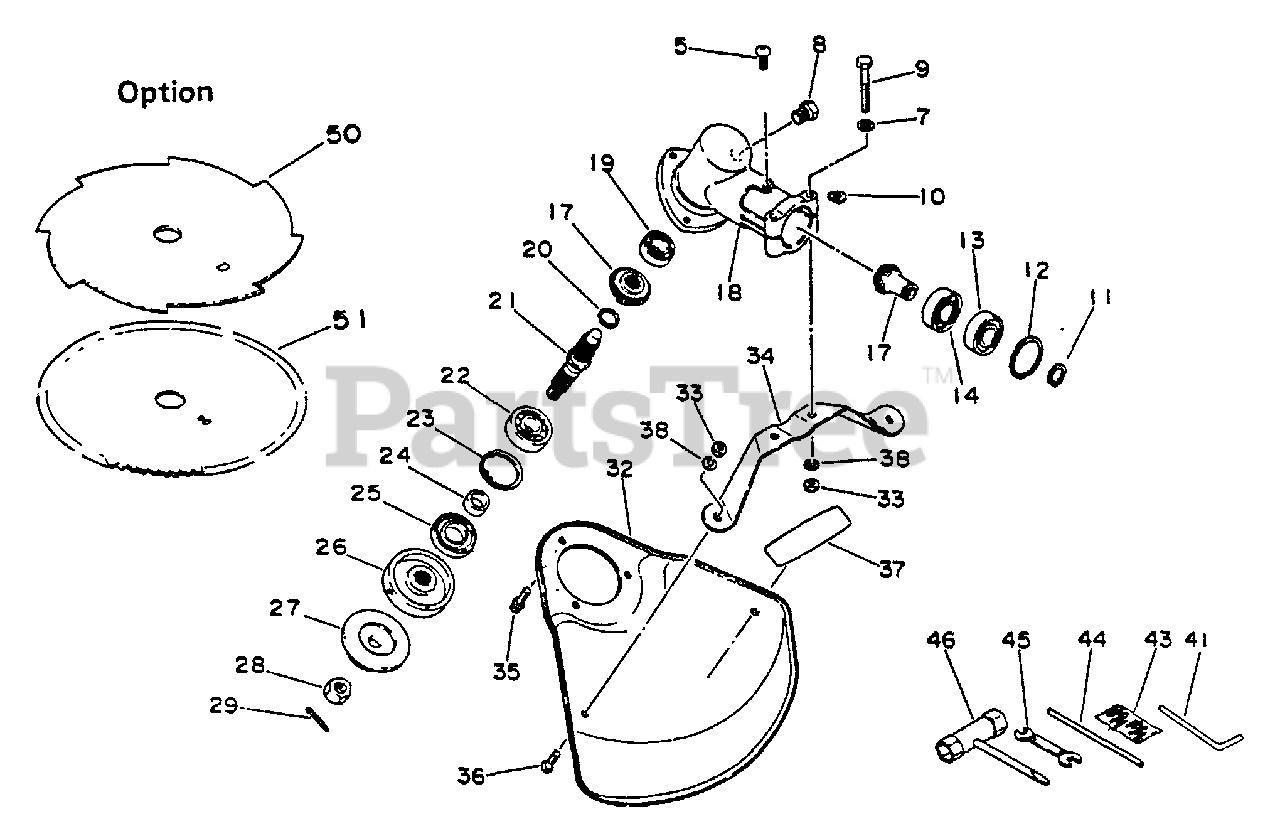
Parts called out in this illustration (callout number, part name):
5	SCREW - 5X10
7	WASHER - 5
8	BOLT - 8X8
9	BOLT - 5X40
11	RING, RETAINING - 12
12	RING, RETAINING - 28
13	BEARING, BALL - 6001
14	BEARING, BALL - 6001
17	GEAR SET - BEVEL
18	CASE, GEAR
19	BEARING, BALL - 6000
20	RING, RETAINING - 12
21	GEAR - SHAFT
22	BEARING, BALL - 6201
23	RING, RETAINING - 32
25	SEAL, OIL
26	ADAPTOR, BLADE - UPPER
27	ADAPTOR, BLADE - LOWER
28	NUT - 10 -- LEFT HAND
29	PIN, SPLIT - 2X22
32	SHIELD
34	BRACKET, SHIELD
35	SCREW - 5X10
36	SCREW - 5X8
37	LABEL - ECHO
38	LOCKWASHER - 5
41	HEX KEY - 4mm
43	PIN, SPLIT - 2X22
44	LOCKING TOOL
45	SPANNER - 8X10mm
46	T-WRENCH
50	BLADE, 25mm ID - 10" (25cm)
51	BLADE, 30 TOOTH - 25mm -- 8"
